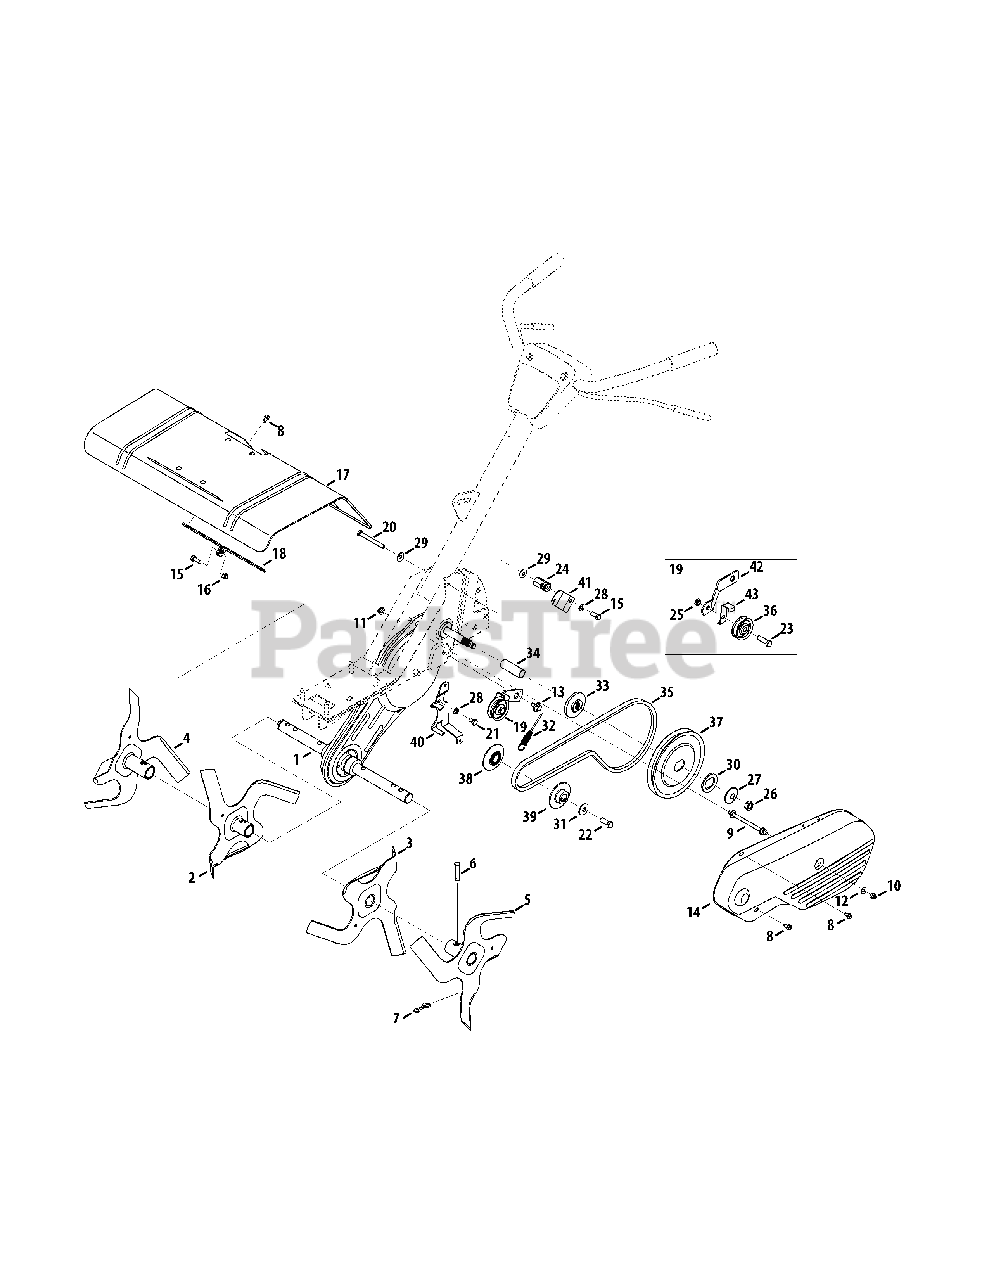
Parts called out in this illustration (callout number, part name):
1	Chain Case Assembly
2	Inner Tine Assembly, RH
3	Inner Tine Assembly, LH
4	Outer Tine Assembly, RH
5	Outer Tine Assembly, LH
6	Clevis Pin, .375 x 1.75
7	Bow Tie Cotter Pin
8	Screw, 1/4-20 x 0.500
9	Bolt, Belt Cover
10	Nut, 1/4-28, Lock
11	Nut, 5/16-18, Flange Lock
12	Flat Washer, .271 x .630 x .065
13	Shoulder Screw, .560 x .165 5/16-18
14	Belt Cover
15	Hex Head Screw, 5/16-18 x .75
16	Nut, 5/16-18, Flange Lock
18	Bracket, Tine Shield
19	Idler Bracket Assembly
20	Hex Head Screw, 5/16-18 x 3.00
21	Hex Head Screw, 5/16-24 x .625
22	Hex Head Screw, 3/8-24 x 1.00
23	Hex Head Screw, 3/8-16 x 1.25
24	Hex Nut, 5/16-18
25	Jamlock Nut, 3/8-16
26	Nut, 1/2-20, Jam
27	Washer, .531 x 1.62 x .045
28	Lock Washer, 5/16
29	Bell Washer, .340 x .872 x .060
30	Flat Washer, 1.26 x 1.87 x .150
31	Bell Washer, .396 x 1.140 x .095
32	Forward Clutch Cable
33	Pulley Adaptor
34	Spacer, .64 ID x 2.4
35	Belt, 4L x 41.9 LG
36	Pulley 1.88 OD
37	Pulley 6.00 OD
38	Inner Engine Pulley
39	Outer Engine Pulley
40	Belt Keeper Bracket
41	Cable Guide Bracket
42	Idler Bracket
43	Belt Keeper
